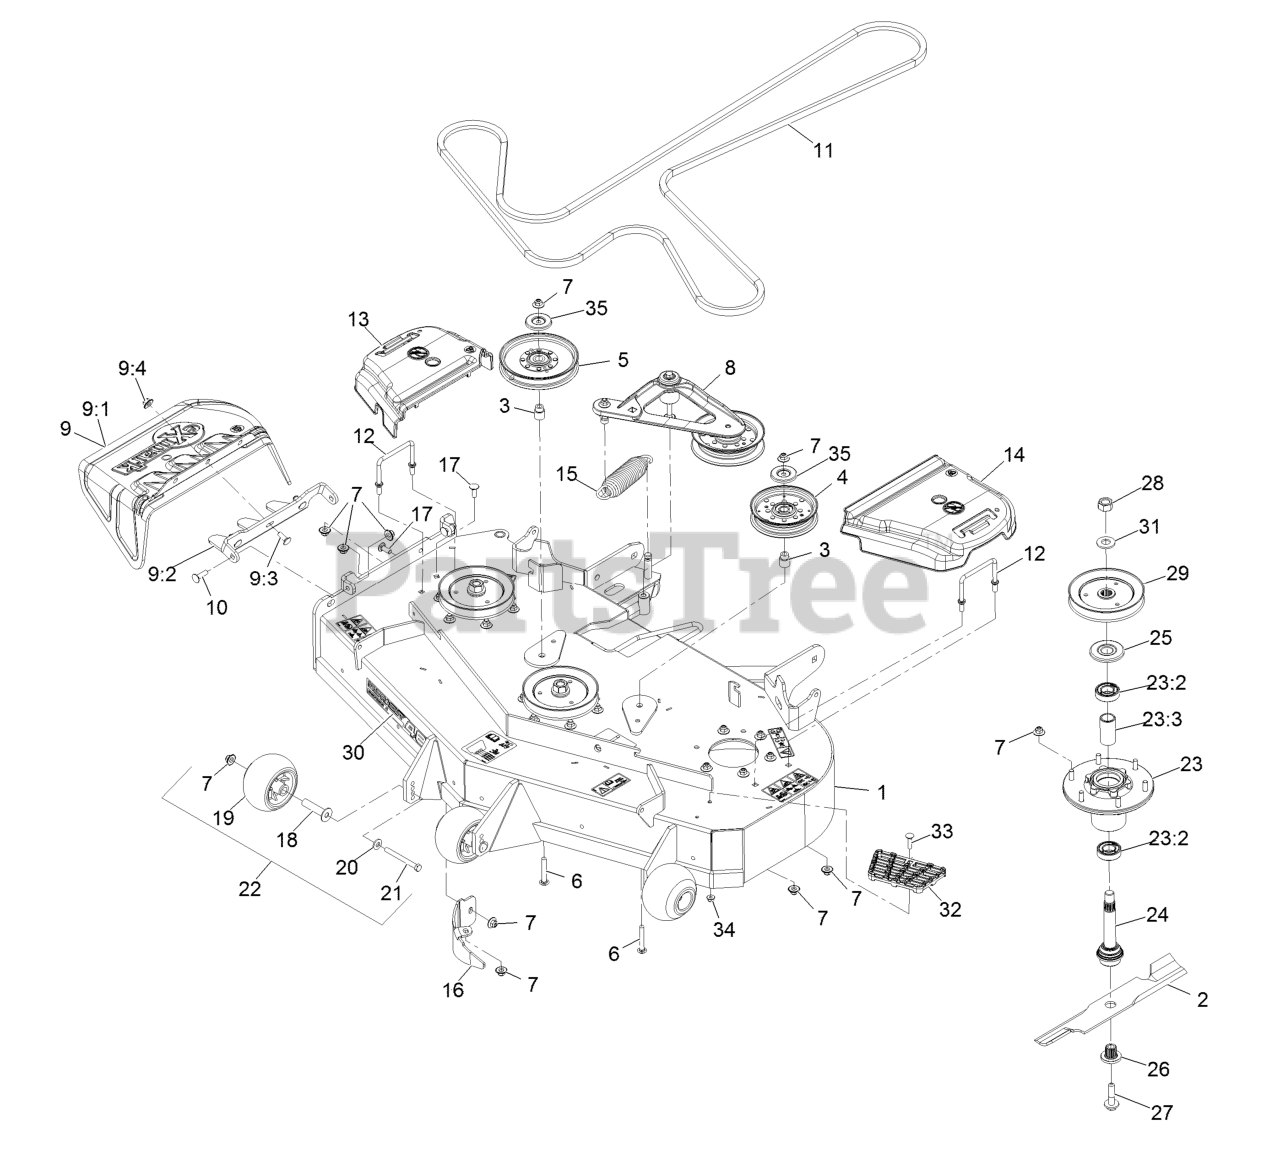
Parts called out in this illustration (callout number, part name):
1	ASM,Deck W/Decals 48
2	Blade, Solid
2	Blade, Low Lift
2	Blade, Mulching
2	Blade-Notched
2	Blade-Extreme 2, 16.25"
3	Bushing, Idler
4	Pulley-Idler, Flat
5	Idler-Pulley
6	Bolt-Carriage 3/8-16 X 2 1/2
7	Nut-Nyloc 3/8-16 Flg
8	Deck Idler ASM
9	ASM,Discharge Chute
9:1	Chute, Discharge
9:2	Bracket,Discharge Chute
9:3	Bolt-Carriage 3/8-16 X 1
9:4	Nut-Nyloc 3/8-16 Flg
10	Bolt-Carriage 3/8-16 X 1 1/4
11	Belt
12	Wireform-Cover
13	Cover-Belt, RH
14	Cover-Belt, LH
15	Spring-Extension
16	Baffle-Dogleg,Lzs Lzx Vt48
17	Bolt-Carriage 3/8-16 X 1
18	Axle, Roller
19	Roller-Anti-Scalp
20	Washer-Spring Disc 3/8
21	Screw-HH 3/8-16 X 3 3/4 GR 8
22	Kit, Anti-Scalp Roller
23	ASM-Cutter Hsg With Bearings
23:2	Bearing-Ball
23:3	Spacer-Bearing
24	ASM-Spindle And Seal
25	Guard,Bearing Top .989
26	Bushing, Splined
27	Screw-Sems 1/2-20 X 2.19
28	Nut-Hex
29	Sheave,Blade Drive 5.90
30	Decal, 484
31	Washer-Spring Disc 3/4
32	Step-Deck
33	Bolt-Carriage 5/16-18 X 1 1/4
34	Nut-Nyloc 5/16-18 Flg
35	Shield-Dust
